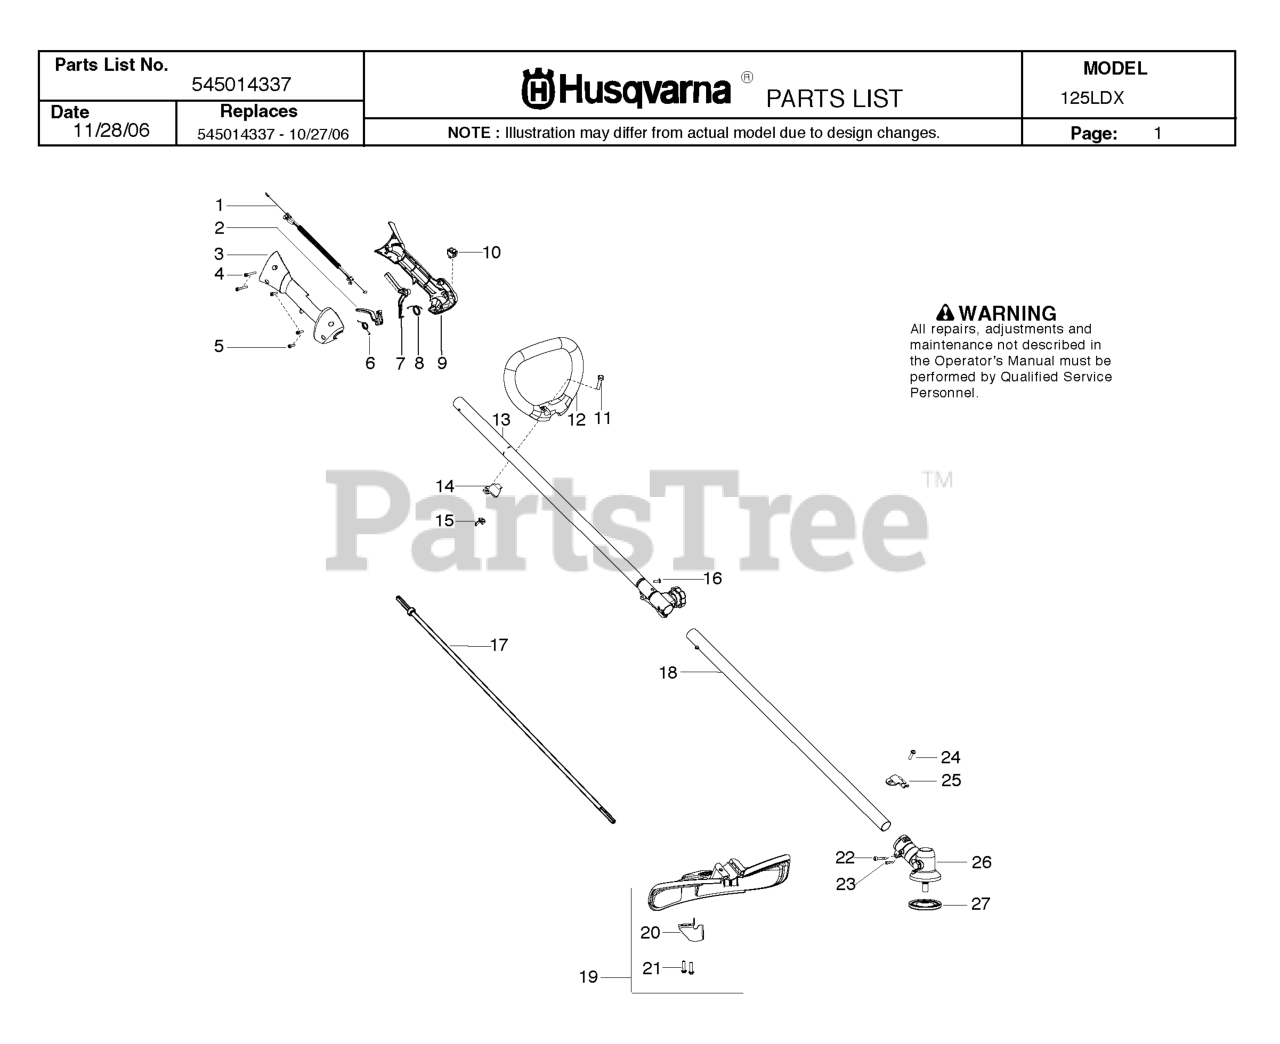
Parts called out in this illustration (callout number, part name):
1	%ASSY CABLE WIRE HARNESS
2	TRIGGER THROTTLE
3	HOUSING-THROTTLE RH
5	SCREW M4 X 1.75 PT 16MM
6	SPRING TRIGGER
7	THROTTLE LOCKOUT
8	SPRING LOCKOUT
9	HSG THROTTLE LH
10	KIT SWITCH
11	BOLT, TYPE 2
13	DRIVE SHAFT
14	CLAMP ASSIST HANDLE
15	WINGNUT, TYPE 2
17	FLEX-LOWER
18	KIT DRIVESHAFT LOWER LDX
19	KIT COBI SHIELD
20	Limiter - Line
22	SCREW - CARB. ADAPTOR
24	SCREW 1/4-20 X 7/8 (TAP
25	BRACKET SHIELD STRAIGHT SHAFT
26	ASSY GEARBOX
27	DRIVE DISC
